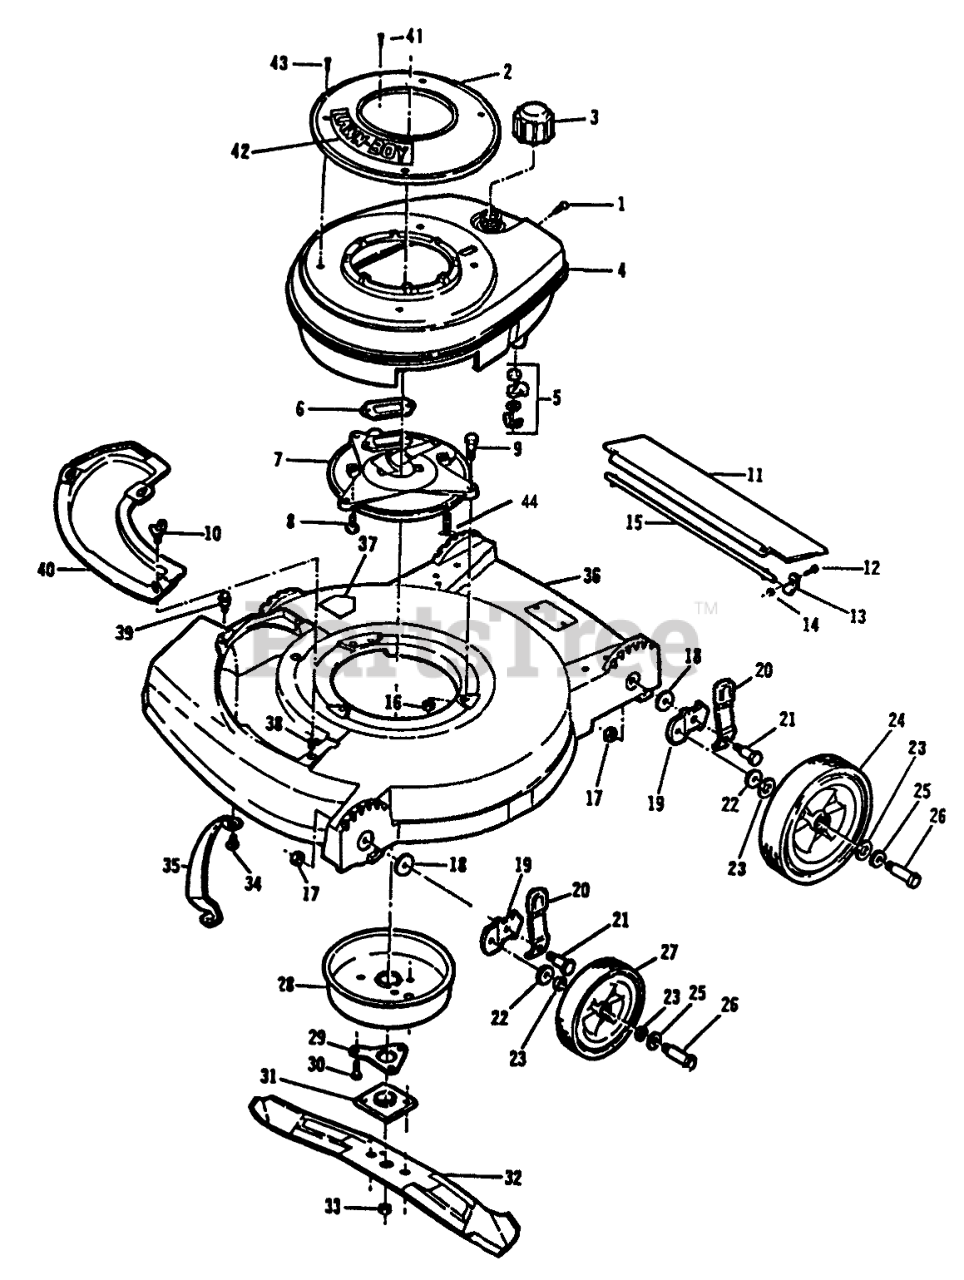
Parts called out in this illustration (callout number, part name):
1	SCREW S
2	STARTER BASE&NUTB
3	FUEL CAP & INSERT
4	Shroud-Engine
5	SHUT OFF VALVE KIT
6	Gasket
7	PLATE F
8	SCREW V
9	SCREW-HH
10	WING SCREW LAWRE
11	SHIELD
12	Screw
13	CLAMP ROD KMC
14	LOCKNUT E
15	ROD T/SHIELD ADV WIRE
16	NUT-LOCK F
17	NUT
18	WASHER
19	Bracket
20	SPRING ARM ASM
21	BOLT
22	WASHER WROUGHT
23	WASHER
24	WHEEL&TIRE AY.
25	WASHER-PLAIN
26	BOLT WHEEL
27	Front Wheel
28	MUFFLER COVER F
29	SUPPORT F
30	SCREW
31	PLATE AND COLLAR ASM
32	Blade 19"
33	NUT-BLADE
34	Screw
35	TOE BAR 19"
36	HSG AY-19" SERVICE
37	Decal
38	Grommet
39	Bolt
40	CoverPlate
41	SCREW SEMS SM
42	APPLIQUE
43	SCREW S
44	SCREW-SEMS F
